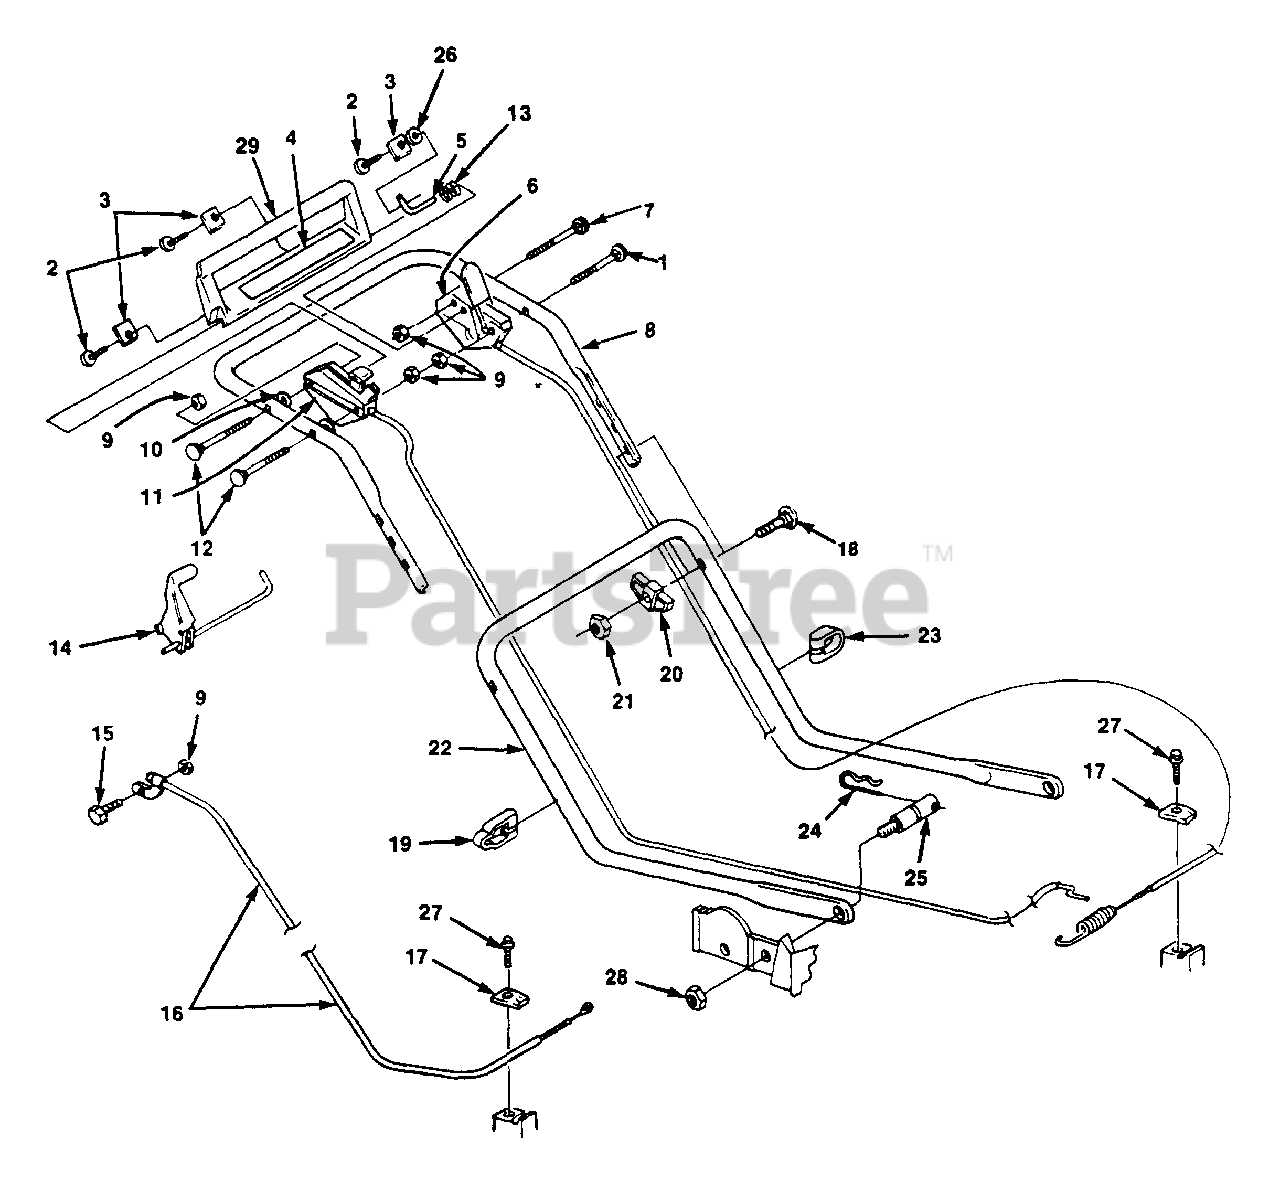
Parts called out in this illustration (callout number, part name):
1	BOLT-SQUARE NECK 2.12
2	SCREW - 1/4-10×5/8" -- ROUND HEAD
3	CLAMP, PIVOT SHAFT
4	LABEL - BRAKE BAIL
5	SHAFT, PIVOT (SHORT)
6	CONTROL-BLADE/BRAKE/CLUTCH
7	BOLT, SQ. NECK 1/4-20×2 1/4
8	HANDLE - UPPER
9	LOCKNUT - 1/4-20
10	SPACER
11	CONTROL, THROTTLE
12	BOLT, SQ. NECK 1/4-20×2
13	SPRING, COMPRESSION
14	TRACTION LEVER
15	SCREW - 1/4-20×1-1/2" -- HEX CAP
16	CABLE, TRACTION
17	CLAMP
18	BOLT
19	CLAMP - DOUBLE
20	KNOB - HANDLE
21	NUT - 5/16-18
22	HANDLE, LOWER
23	CLAMP - CABLE SINGLE
24	PIN, COTTER
25	STUD
26	WASHER - 1/4"
27	SCREW 1/4"×5/8
28	NUT - 5/16-18 -- FLANGE
29	BAIL - BRAKE CONTROL
